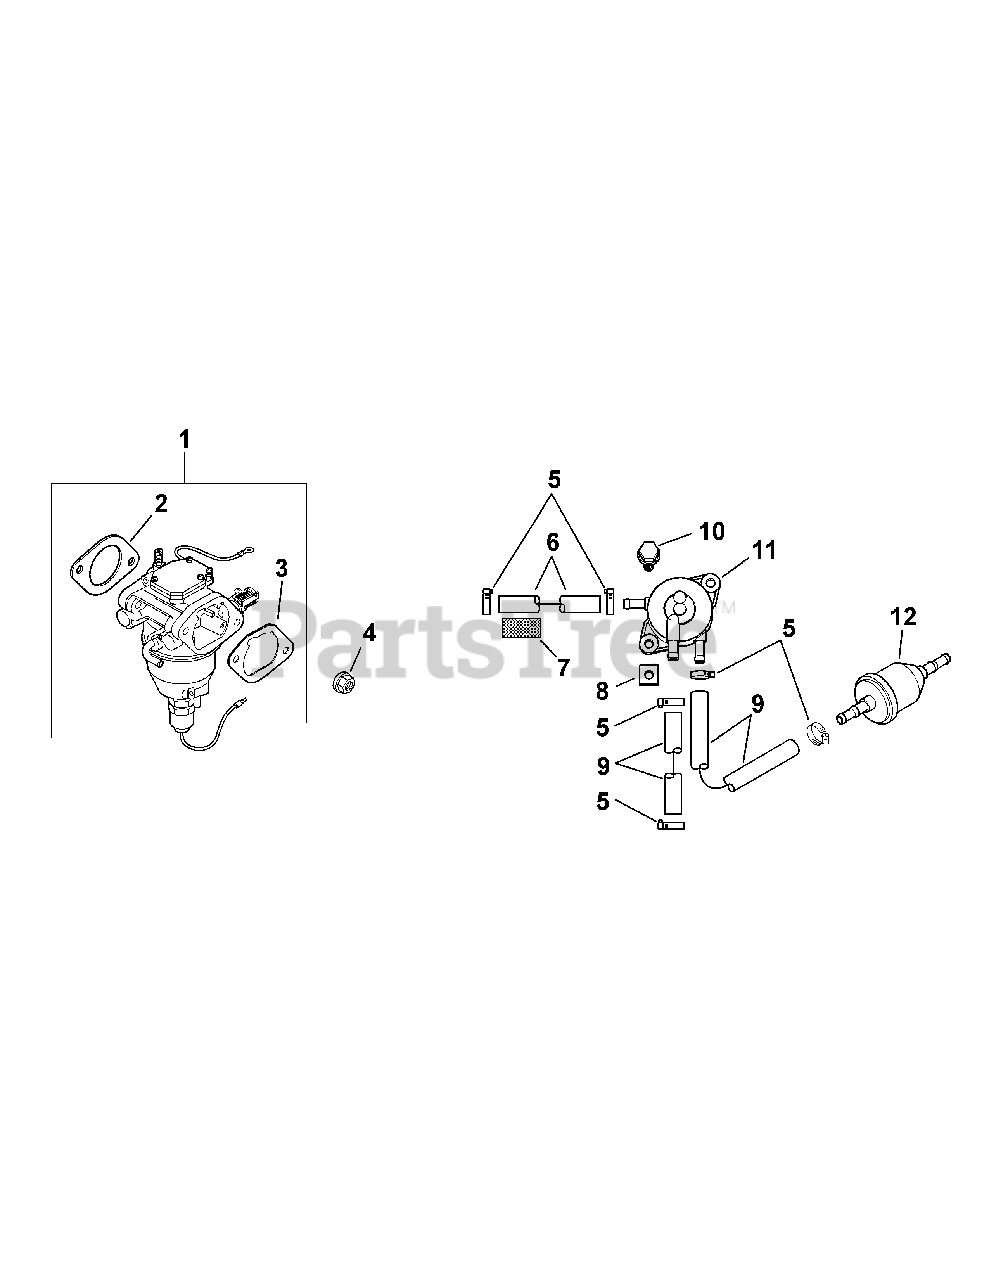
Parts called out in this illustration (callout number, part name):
1	Carburetor Kit w/ Gaskets (Inc. 2 & 3)
2	Carburetor Gasket
3	Air Cleaner Base Gasket
4	Flange Nut, M6 x 1.0
6	Flex Line, 11"
7	Insulating Sleeve, 14"
9	Fuel Line, 24"
10	Tap Screw, M6 x 1.7 x 18
